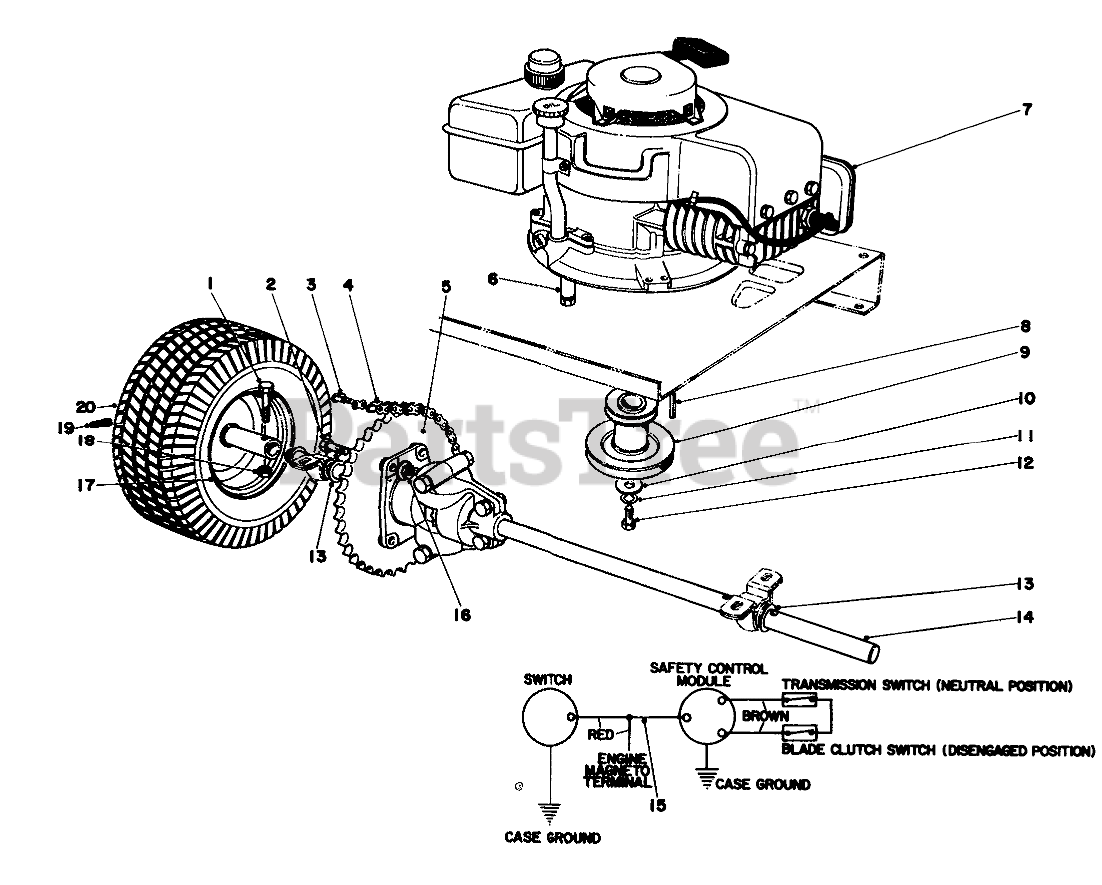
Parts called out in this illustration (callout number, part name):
1	SCREW-HH
2	SCREW-HH
3	LINK-CONNECTING
4	Roller Chain
5	Sprocket
6	Extension Oil Drain
7	Engine
9	Pulley
10	Washer
11	WASHER-LOCK
12	SCREW-HH
13	WASHER
14	Differential
15	Wiring Harness
16	NUT-LOCK, CONE
18	NUT-LOCK, CONE
19	STEM-VALVE
20	Tire
